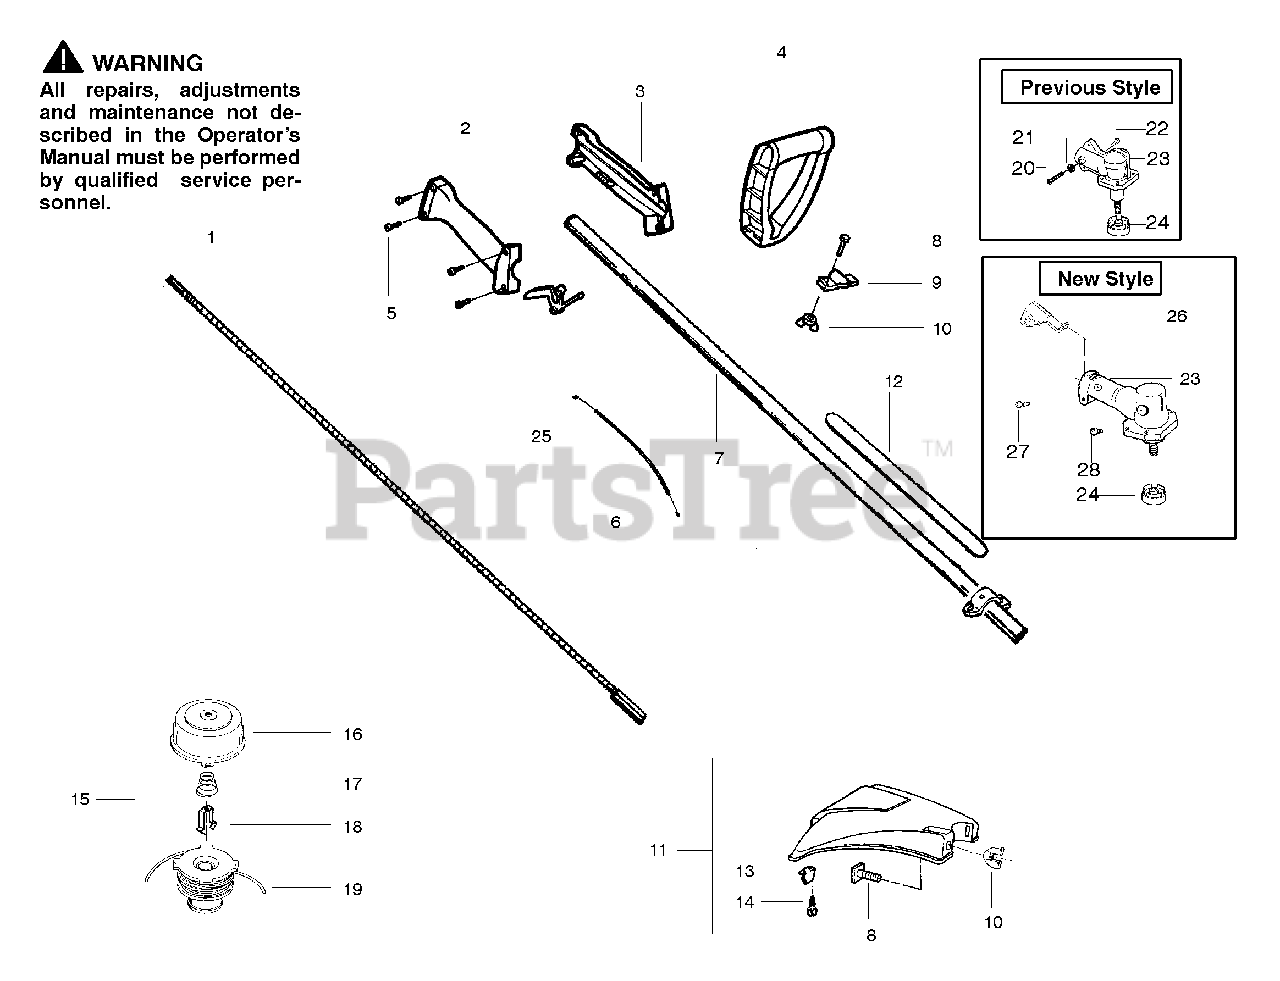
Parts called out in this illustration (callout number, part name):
1	Shaft- Flex-52" (type 1,2)
1	Shaft- Flex-52" (type 3,4,5)
2	Throttle Hsg. (Right)(type 1,2)
2	Throttle Hsg. (Right)(type 3,4,5)
3	Throttle Hsg. (Left)(type 1,2)
3	Throttle Hsg. (Left)(type 3,4,5)
4	Assist Handle
5	Screw-Throttle Hsg.
6	Throttle Cable Ass'y.(type 1)
6	Throttle Cable Ass'y.(type 2,3,4,5)
7	Assy-Drive Shaft (type 3,4,5)
9	Clamp-Handle
10	Wingnut
11	Kit-Shield Assy.
12	Shaft Warning Decal
13	Line Limiter
14	Screw-Line Limiter
15	Cutting Head Ass'y.
16	Hub Ass'y.
17	Spring-Return
18	Retainer-Spool
19	Spool w/Line
20	Screw-Gear Box
21	Lockwasher-Gear Box
23	Assy-Gear Box
24	Dust Cup
